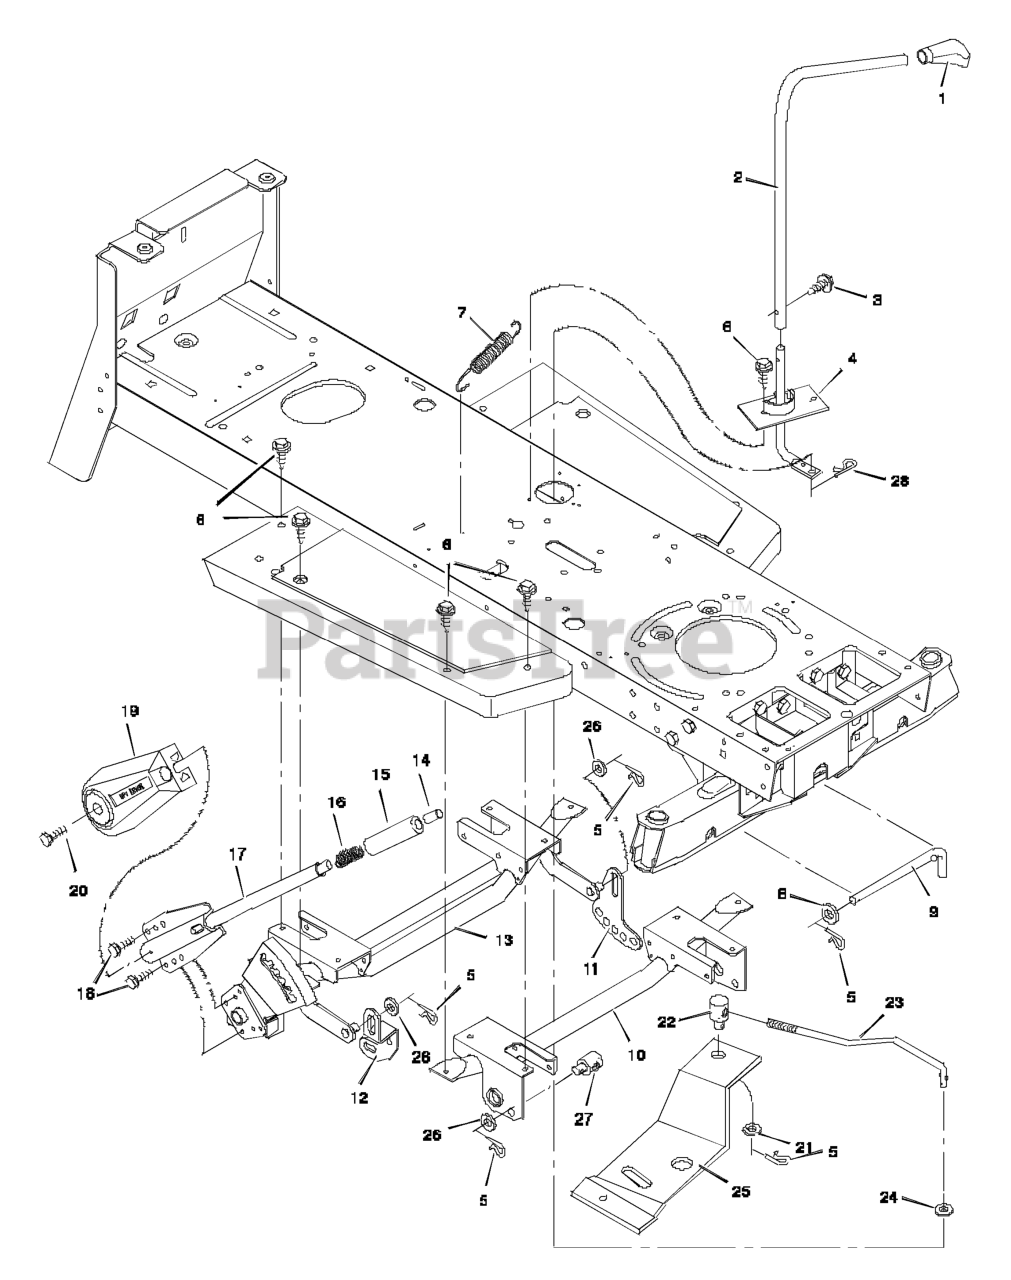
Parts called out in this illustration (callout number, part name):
1	Grip
2	Lever, Blade Control
3	Screw, Hex
4	Control Assembly, Blade
5	Pin, Hair
7	Spring, Extension
9	Pin, Pull
10	Support Assembly, Front
11	Plate, Adjuster
12	Link, Suspension
13	Support, Lifter
14	Button, Push
16	Spring, Compression
17	Handle Assembly
19	Cover, Lift Lever
22	Nut, Adjusting
23	Rod, Blade Control
24	Washer
25	Bracket, Pivot
27	NUT, Adjusting, 1/2-13
28	Pin, Hair
